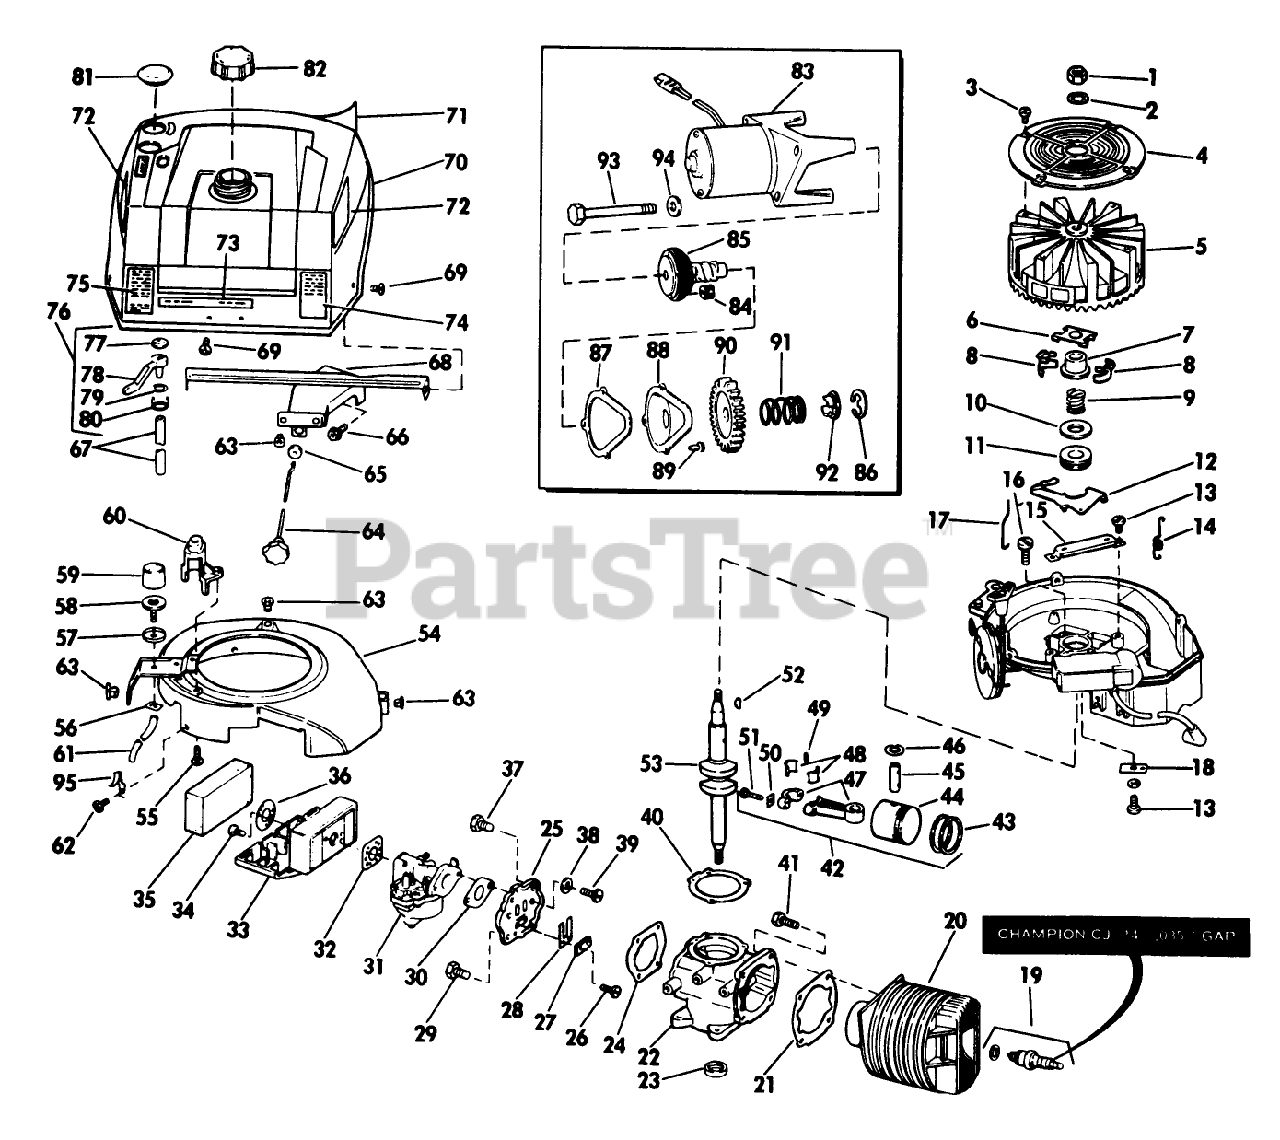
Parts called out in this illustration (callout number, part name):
3	SCREW F
7	COLLAR S
9	SPRING S
12	LEVER-GOVERNOR S
13	SCREW S
15	BRACKET
19	Spark Plug Champion CJ-14 .035" Gap
21	GASKET S
24	GASKET S
25	REED PLATE AY. S
27	PLATE-BACKUP, REED
29	SCREW S
30	GASKET S
32	GASKET S
34	SCREW S
35	AIR FILTER S
36	WASHER S
37	SCREW S
40	GASKET S
46	RING-RETAINING
48	LINER ASM
56	Fastener
57	CUP-BULB
63	NUT-CLIP
64	Knob Rod
66	SCREW S
68	BRACKET
79	WASHER S
86	RET.RING EF
